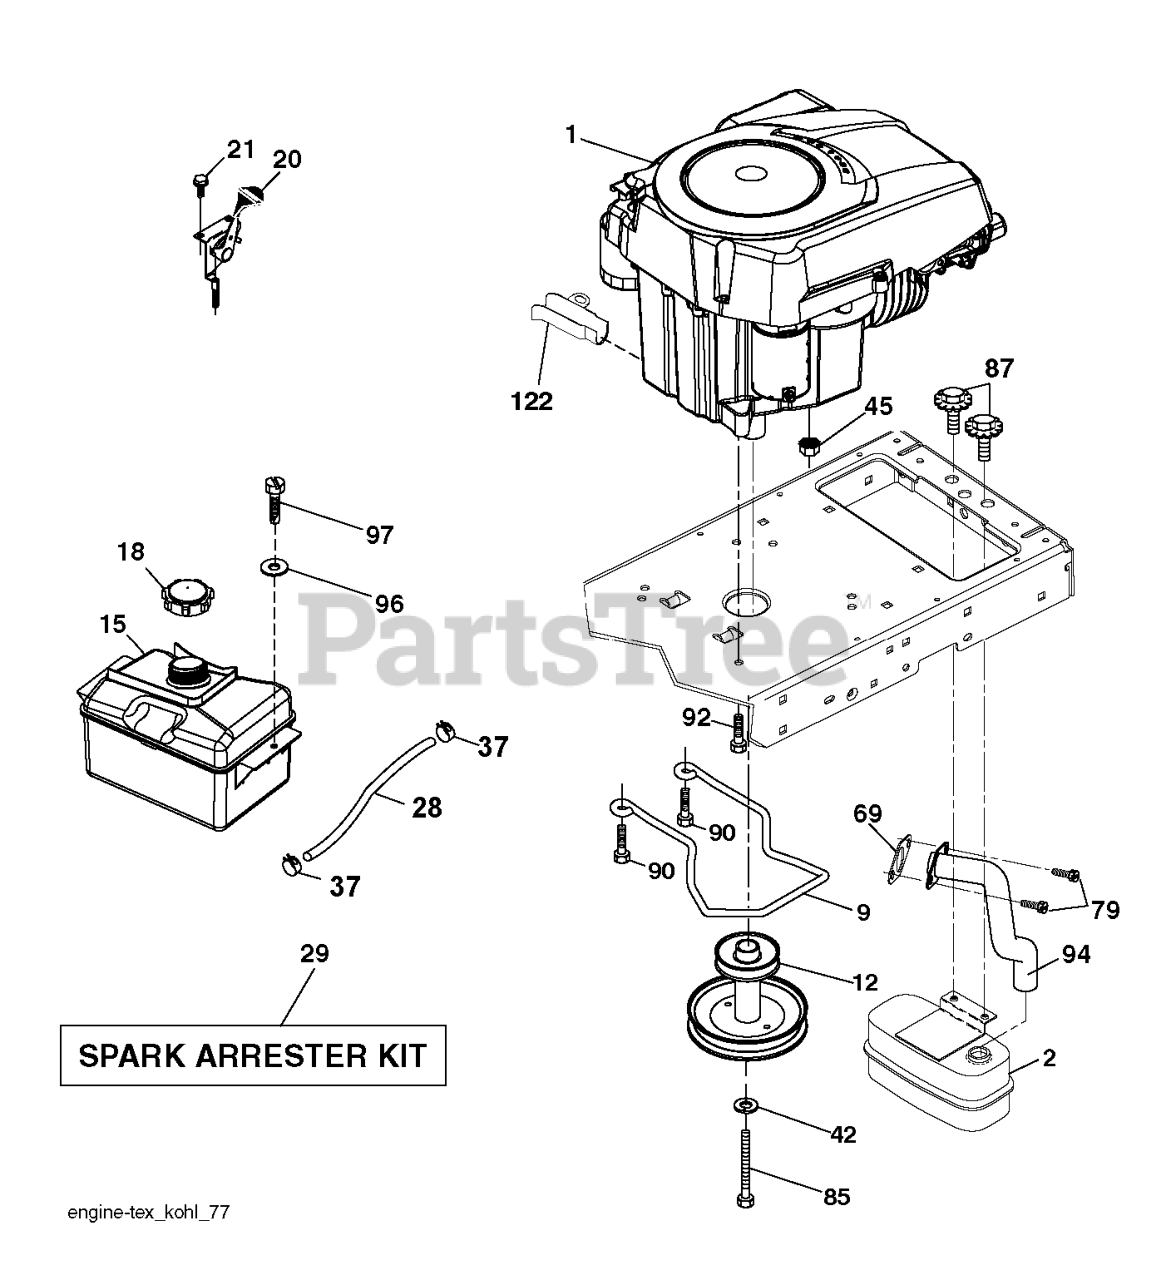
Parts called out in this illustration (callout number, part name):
1	STARTER ASSY
3	STARTER PULLEY
4	RECOIL SPRING
6	STARTER DEVICE
7	STARTER HANDLE
8	STARTER ROPE
9	SCREW IHSCFM
10	LABEL STARTAP.343F
12	LABEL STARTAP.345FXT
13	LABEL STARTAP.343R
15	LABEL STARTAP.343FR
16	LABEL STARTAP.345FRM
